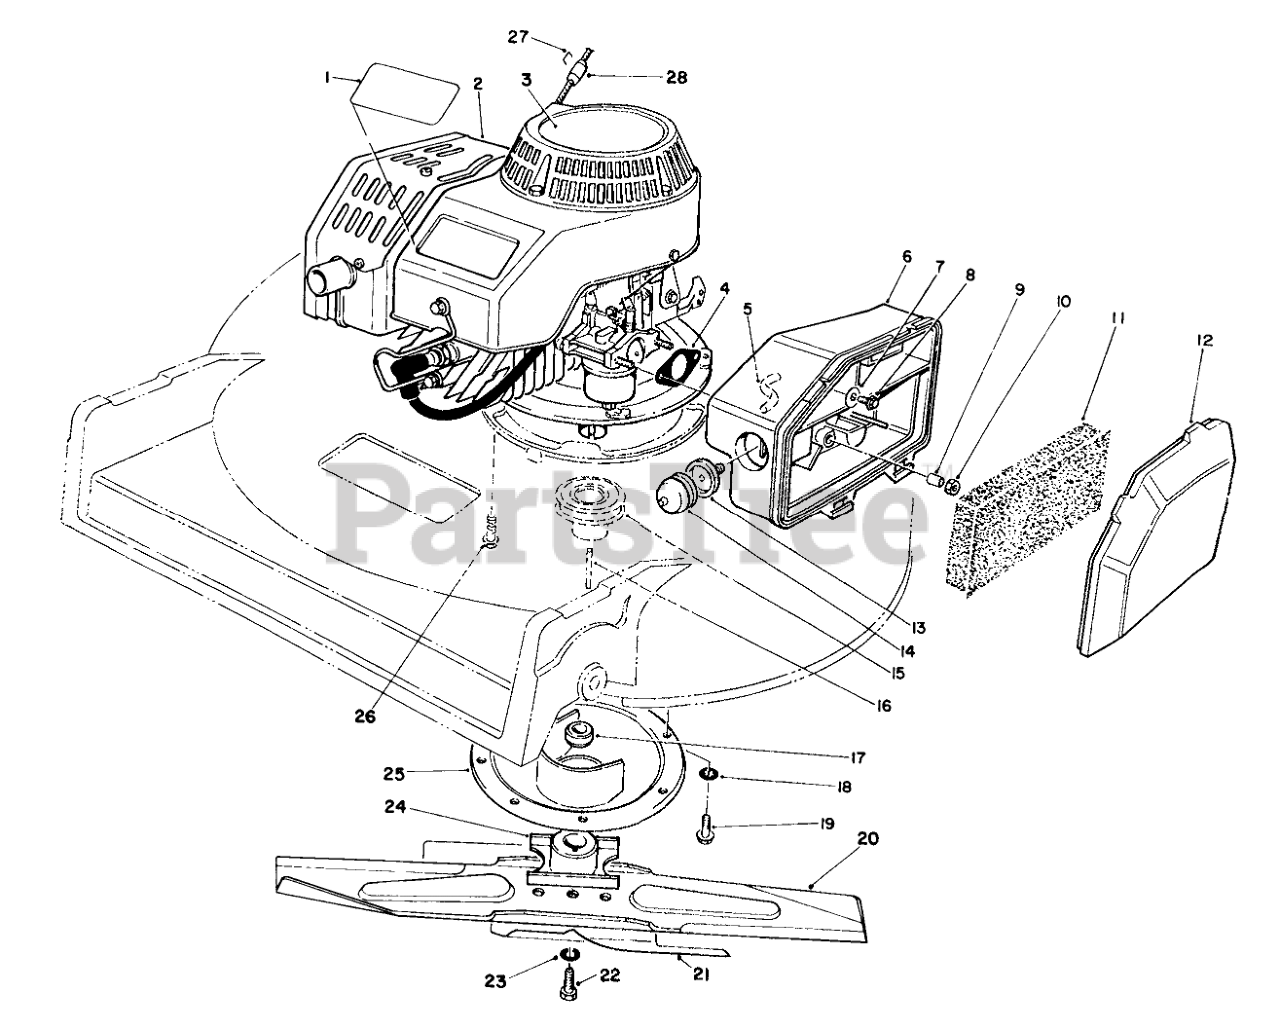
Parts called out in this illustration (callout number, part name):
1	DECAL - PROLINE
2	ENGINE ASM
3	DECAL-2 CYC RECOIL COMM
4	GASKET-AIR CLEANER
5	HOSE-PRIMER
6	BODY-AIR CLEANER
7	WASHER-FLAT
8	SCREW-HH
9	SPACER
11	ELEMENT-AIR CLEANER
12	COVER-AIR CLEANER
13	BODY-PRIMER
14	BULB-PRIMER
15	PULLEY-DRIVER
16	KEY-SQUARE
17	SPACER-BLADE RETAINER
18	WASHER-LOCK, INTERNAL
19	SCREW-HWHTF
20	Blade
21	Accelerator
22	SCREW-BLADE
23	WASHER-LOCK
24	RETAINER-BLADE
25	PROTECTOR-CRANKSHAFT
26	SCREW-HHF
27	Staple
28	STOP-ROPE
